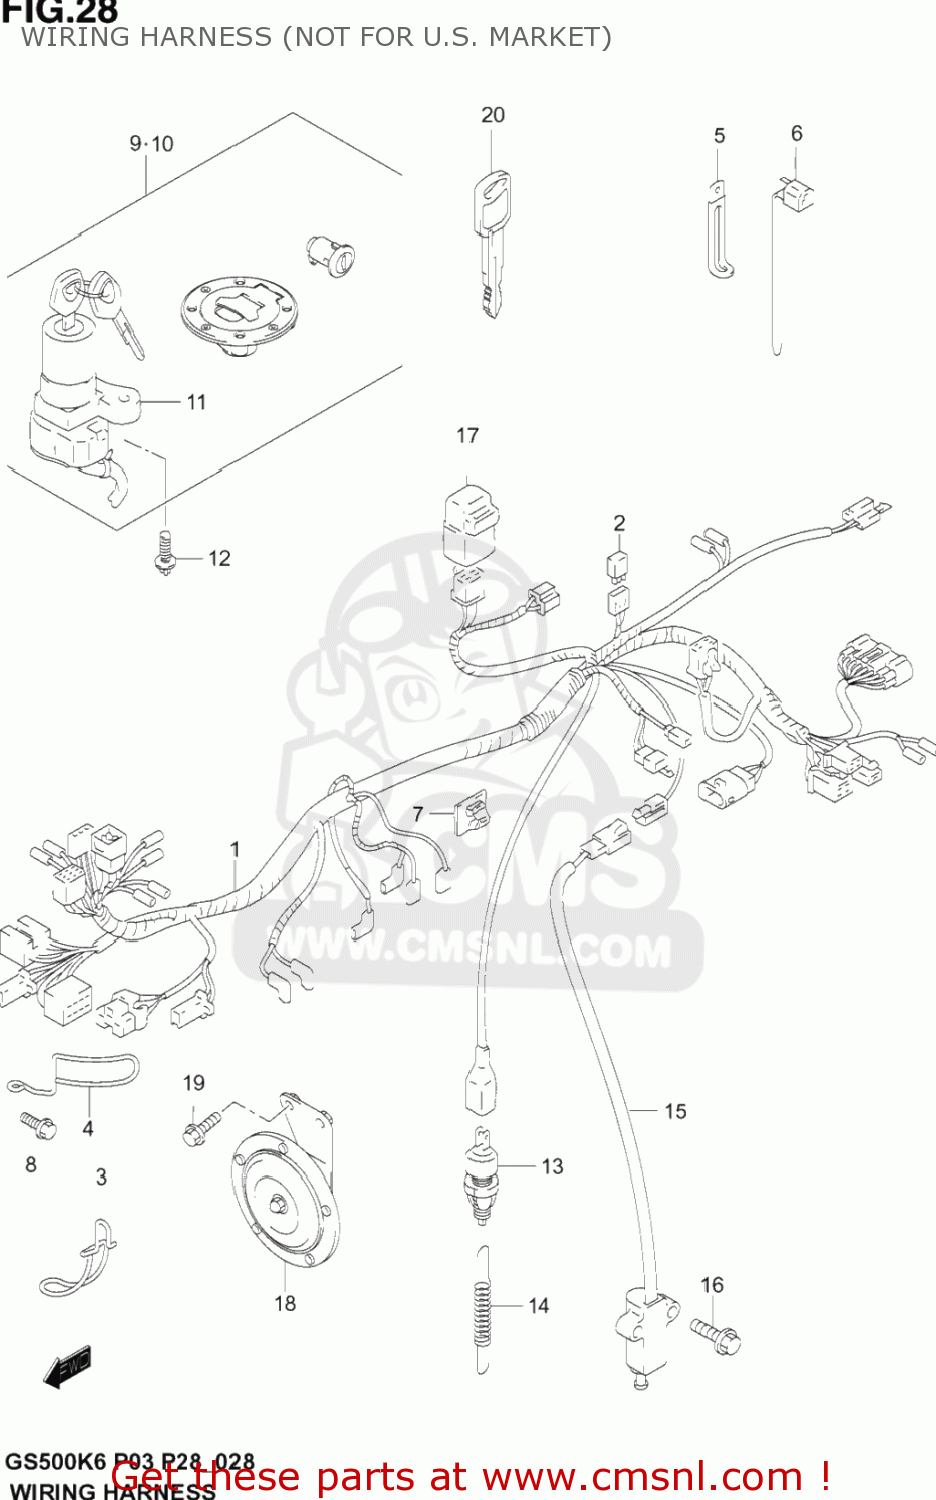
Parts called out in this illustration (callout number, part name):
1	HARNESS,WIRING
2	DIODE
3	PROTECTOR
4	PROTECTOR
5	CLAMP(L:45)
6	CLAMP(L:125)
7	CLAMP
8	BOLT
9	LOCK SET
10	LOCK SET
11	LOCK ASSY,STEERING
12	SCREW(6X18)
13	SWITCH ASSY,STOP LAMP
14	SPRING
15	SWITCH ASSY,SI
16	BOLT
17	RELAY ASSEMBLY
18	HORN ASSY
19	BOLT OIL LEVEL
20	KEY,BLANK
